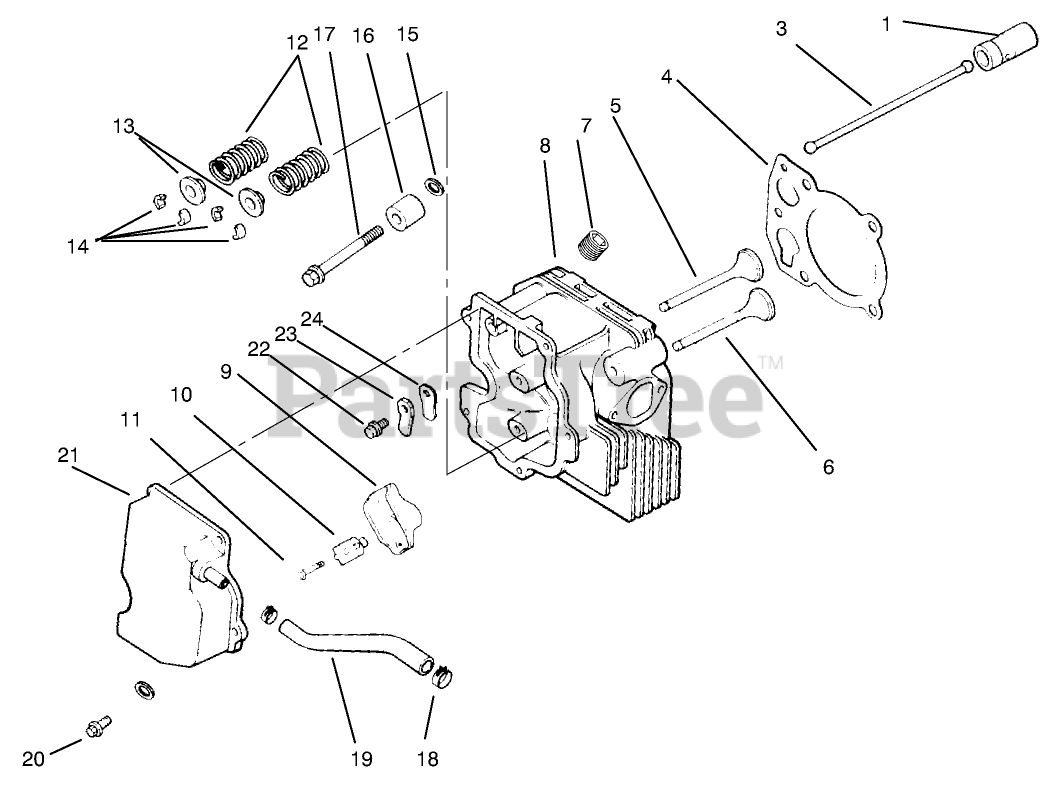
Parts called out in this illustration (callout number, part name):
1	Lifter-Valve
3	Rod-Push
4	Gasket-Head, Cylinder
5	Valve-Intake (STD)
5	Valve-Intake (.25)
6	Valve-Exhaust (STD)
6	Valve-Exhaust (.25)
7	PLUG-PIPE, COUNTERSUNK (1/8)
8	Cylinder Head
9	ARM-ROCKER
10	Pivot-Arm, Rocker
11	SCREW-FLANGE (M6X1.0X34)
12	Spring-Valve
13	CAP-SPRING, VALVE
14	RETAINER KIT
15	Washer-Flat (1/2)
16	Spacer-Head Bolt (Exhaust Port)
17	Screw, M10x1.5x81
18	CLAMP-HOSE, SPRING (1/2)
19	Hose-Breather
20	SCREW-HHFTF (M6X1.0X20)
21	Cover-Valve w/Nipple
22	SCREW-HHFTF (M5X.80X10)
23	Retainer-Reed, Breather
24	Reed-Breather
